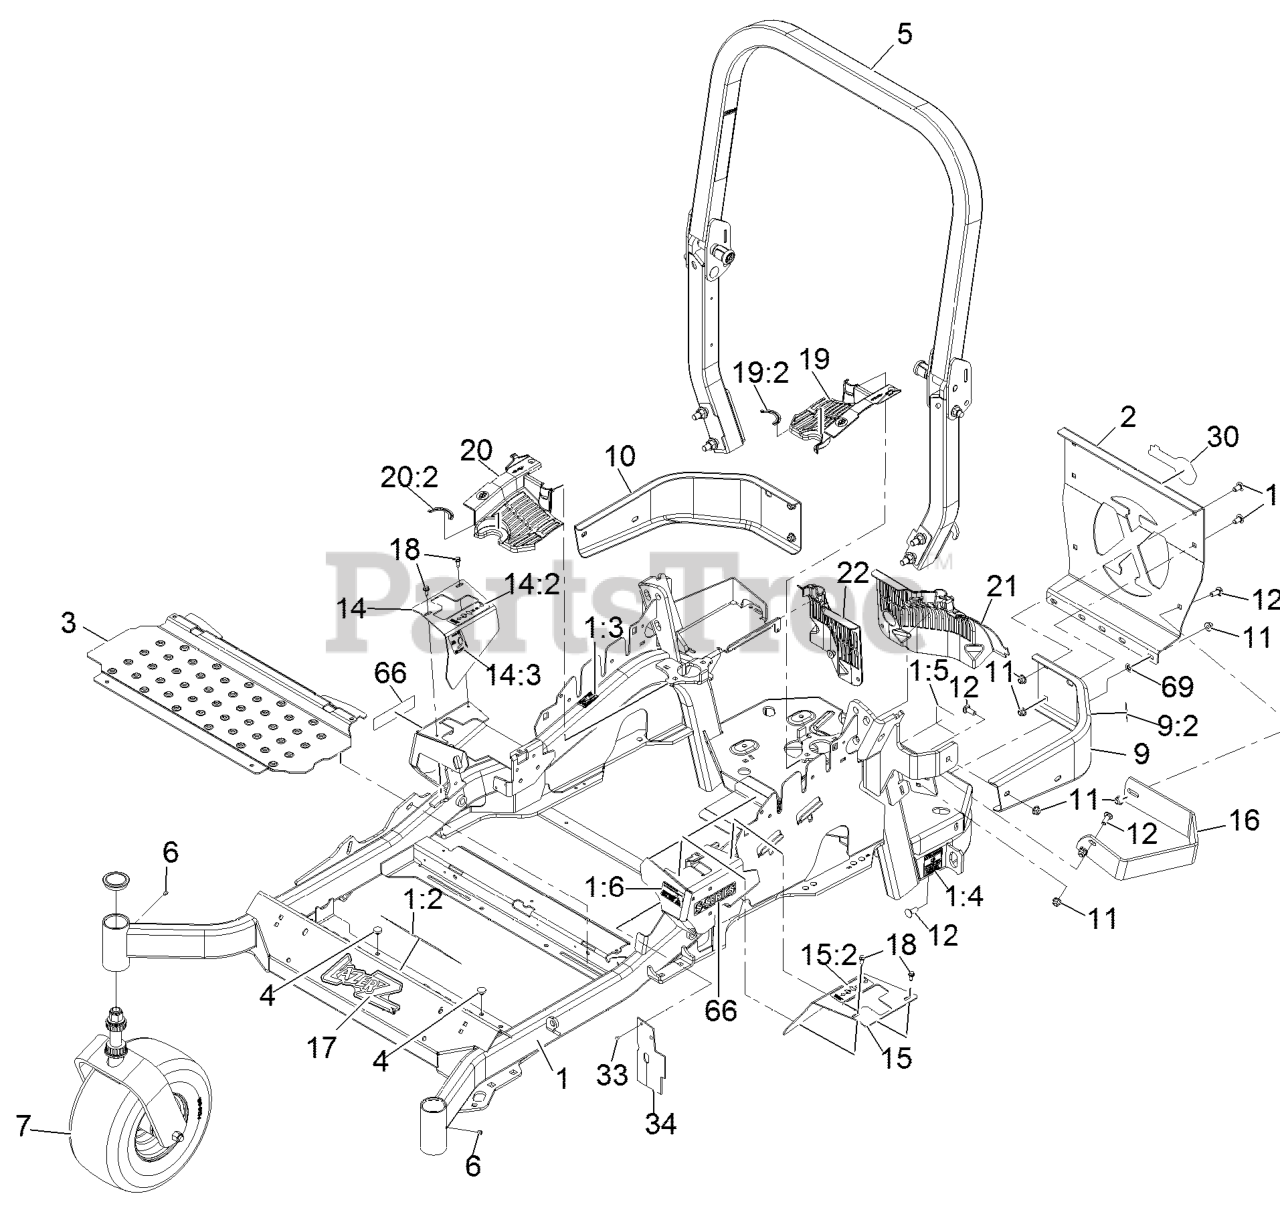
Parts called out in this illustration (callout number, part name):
1	MAINFRAME ASM
1:2	DECAL-SLOPE
1:3	DECAL-CAUTION
1:4	DECAL-BELT DRIVE
1:5	DECAL-SPARK ARRESTER
1:6	DECAL-FUEL FILL
2	PLATE,REAR GUARD
5	ASM,ROPS SERVICE EXMARK
7	Asm,Front Caster W/Fork
9	LH BUMPER ASM
9:2	DECAL-CAUTION
10	BUMPER-RH
11	NUT-HF, NI
12	SCREW-CARR
13	SCREW-CARR
14	RH MOTION CONTROL COVER ASM
14:2	DECAL-MOTION CONTROL
14:3	DECAL-PARK BRAKE
15	LH MOTION CONTROL COVER ASM
15:2	DECAL-MOTION CONTROL
17	DECAL,LAZER MODEL
18	SCREW-HWH
19	LH HYDRO GUARD ASM
19:2	DECAL-HYDRO OIL
20	RH HYDRO GUARD ASM
20:2	DECAL-HYDRO OIL
21	GUARD-HYDRO, REAR (LH)
22	GUARD-HYDRO, REAR (RH)
33	RIVET-POP
34	DEFLECTOR-AIR FLOW
66	DECAL-S-SERIES
69	NUT-PUSH
